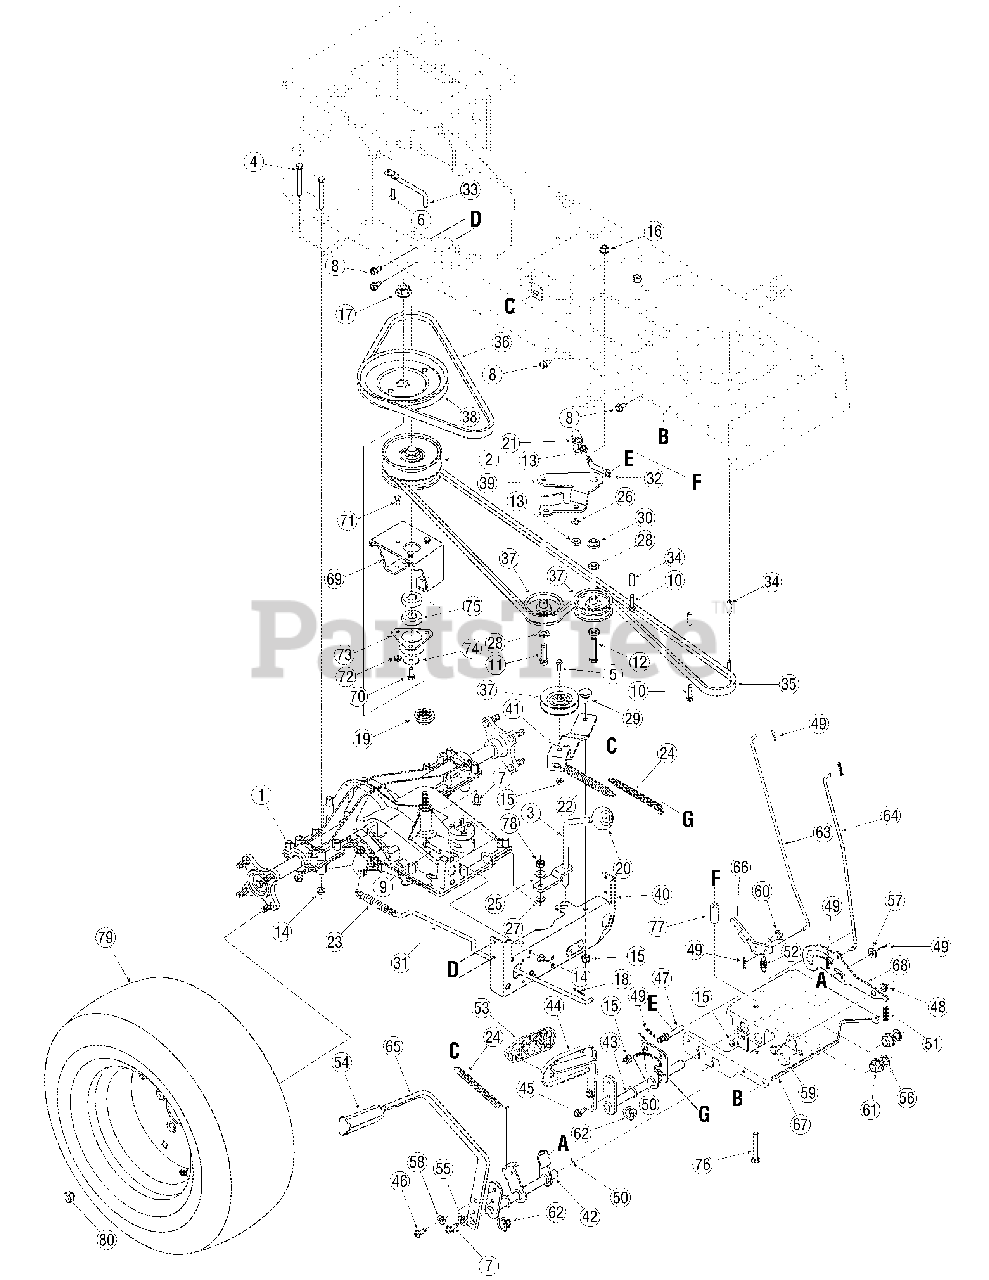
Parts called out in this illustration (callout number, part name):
1	Transmission Assembly, 2-Speed
2	Pulley Assembly, Variable Speed
3	Rod Assembly, Shift, 2-Speed
4	Screw, 5/16-18, 2.75, Gr5
5	Screw, 3/8-16, 1.75, Gr5
6	Screw, 1/4-20, 0.750
7	Screw, 5/16-18, 0.875
8	Screw, 5/16-12, 0.750
9	Screw, 5/16-18, 1.50, Gr5
10	Screw, 1/4-20, 1.250
11	Screw, Sems, 3/8-16, 1.500
12	Screw, 3/8-16, 2.25, Gr5
13	Nut, Hex, 3/8-24, Gr5
14	Nut, Flange Lock, 5/16-18, GrF, Nylon
15	Nut, Flange Lock, 3/8-16, GrF, Nylon
16	Nut, Flange Lock, 3/8-16, GrF,
17	Nut, Flange, 7/16-20, Gr2
18	Pin, Cotter, 3/32 x.750
19	Hub, Pulley, 1/2 Spline
20	Knob, Shift
21	Ball, Joint
22	Extension, Spring 6.12
23	Spring, Extension,.59 OD x 4.00
24	Spring, Extension,.50 Dia x 6.37
25	Washer, Bell,.375 x.870 x.063
26	Washer, Lock, 3/8, Regular Duty
27	Washer, Flat,.44x.75x.06, Ht Spcl
28	Washer, Flat,.407x.812x.135, Ht
29	Screw, Shoulder,.625 Dia x.217
30	Spacer, Shoulder, 1.00 x.38 x.38
32	Adjustment Rod, Idlr, 3/8
33	Rod, Belt Guard
34	Spacer,.260 x.372 x 1.030
35	Belt, V-Type
36	Belt, V-Type
37	Pulley, Flat Idler, 2.75
38	Pulley, V-Type, 8.50
45	Screw, 5/16-18, 0.750
46	Screw, 5/16-18, 0.750
47	Pin, 3/8-16 x 2.68
48	Nut, Flange Lock, 5/16-18, Gr5
49	Pin, Cotter,.072 Dia. x 1.13
50	Pin, Cotter, 3/32, 1.0
51	Spring, Compression,.405 x 1.17
52	Spring, Extension,.50 OD x 1.41
53	Pad, Drive Control
54	Pad, Brake
55	Washer, Lock, 5/16, Regular Duty
56	Washer, Flat,.64 x 1.24 x.06
57	Washer, Flat,.385 x.870 x.092
58	Washer, Flat,.344 x.750 x.120
59	Shoulder Screw.437 Dia x.162
60	Screw, Shoulder,.50 x.27, 3/8-16
61	Bearing, Hex Flange
62	Bearing, Hex Flange,.628 ID, Split
63	Control Rod, Brake Lock
64	Control Rod, Cruise
68	Bracket, Lockout
69	Pulley Bracket
70	Screw, 5/16-24,.75
71	Screw, 1/4-20,.75
72	Nut, Flange Lock, 1/4-20
73	Bearing Cup
74	Washer, Flat,.330 x 1.25 x.06
75	Ball Bearing
76	Screw, 3/8-16, 2.25
77	Spacer,.385 x.635 x 1.54
78	Nut, Jam Lock, 3/6-16
80	Lug Nut, 7/16-14
